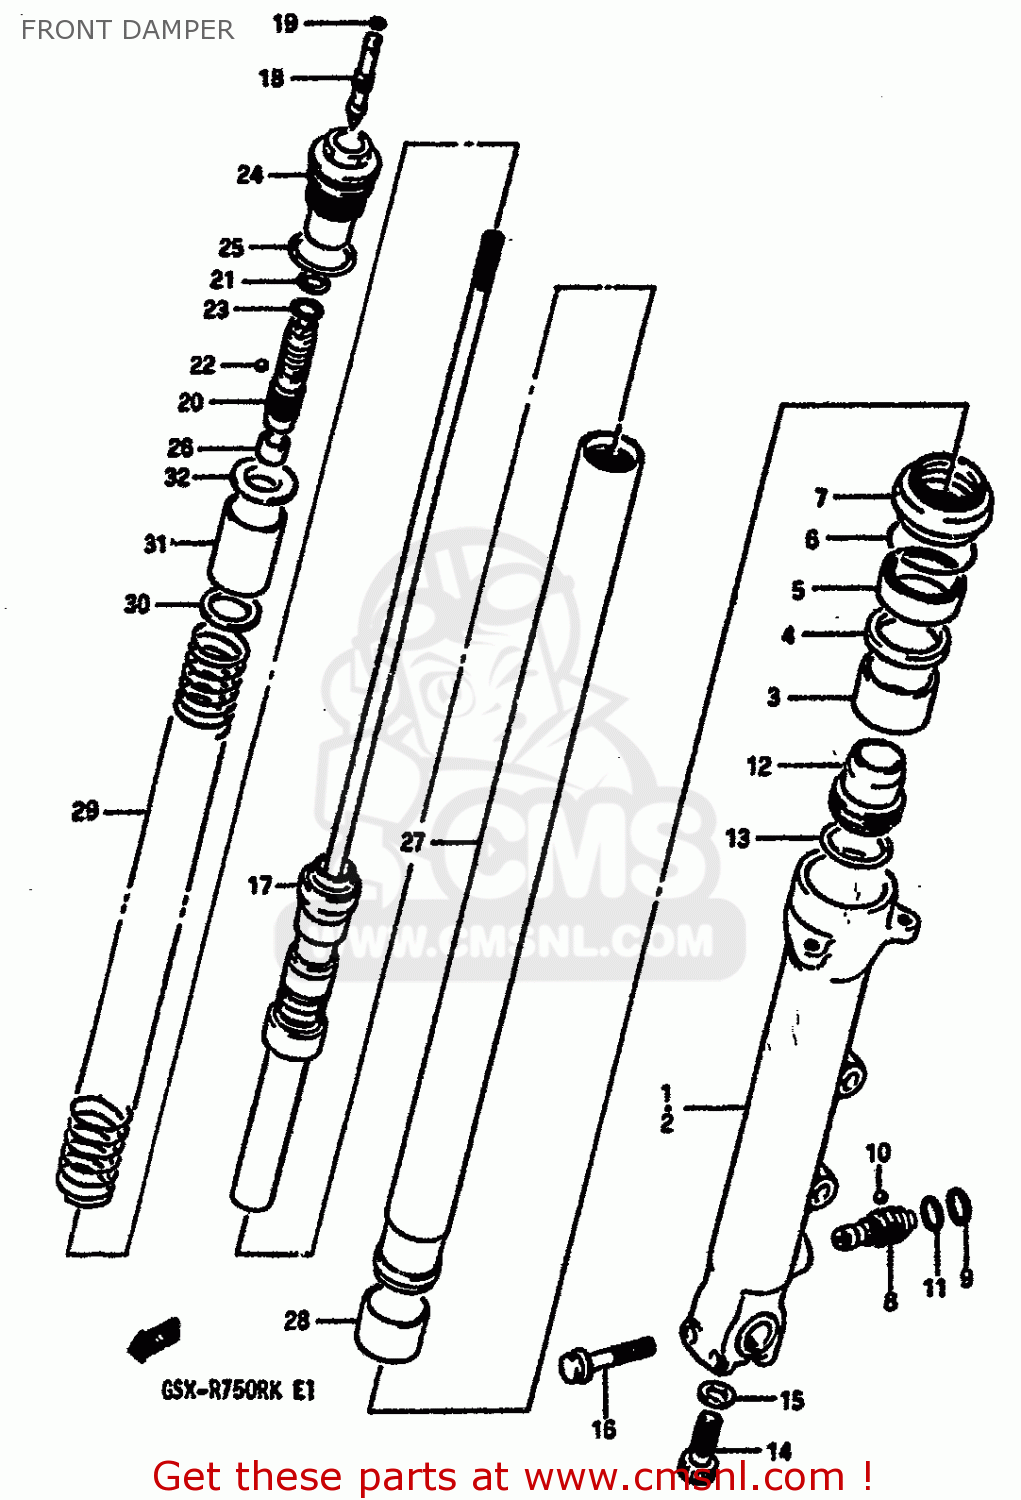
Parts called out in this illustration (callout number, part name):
1	TUBE,OUTER RH
2	TUBE,OUTER LH
3	BUSH,GUIDE
4	SPACER,SEAL
5	OIL SEAL,FRONT FORK
6	CIRCLIP,FORK OIL SEAL
7	SEAL DUST
8	PIECE,ADJUSTER
9	O RING
10	BALL
11	EXPANDER
12	PIECE,OIL LOCK
13	O RING
14	BOLT
15	WASHER(10X15X1.5)
16	BOLT
17	DAMPER
18	PIECE,ADJUSTER UPR
19	O RING
20	ADJUSTER,SPRING
21	O RING
22	BALL
23	EXPANDER
24	BOLT,FORK
25	O RING
26	NUT
27	TUBE,INNER
28	BUSH,SLIDE
29	SPRING
30	SEAT,SPRING LWR
31	COLLAR,SPRING
32	SEAT,SPRING UPR
